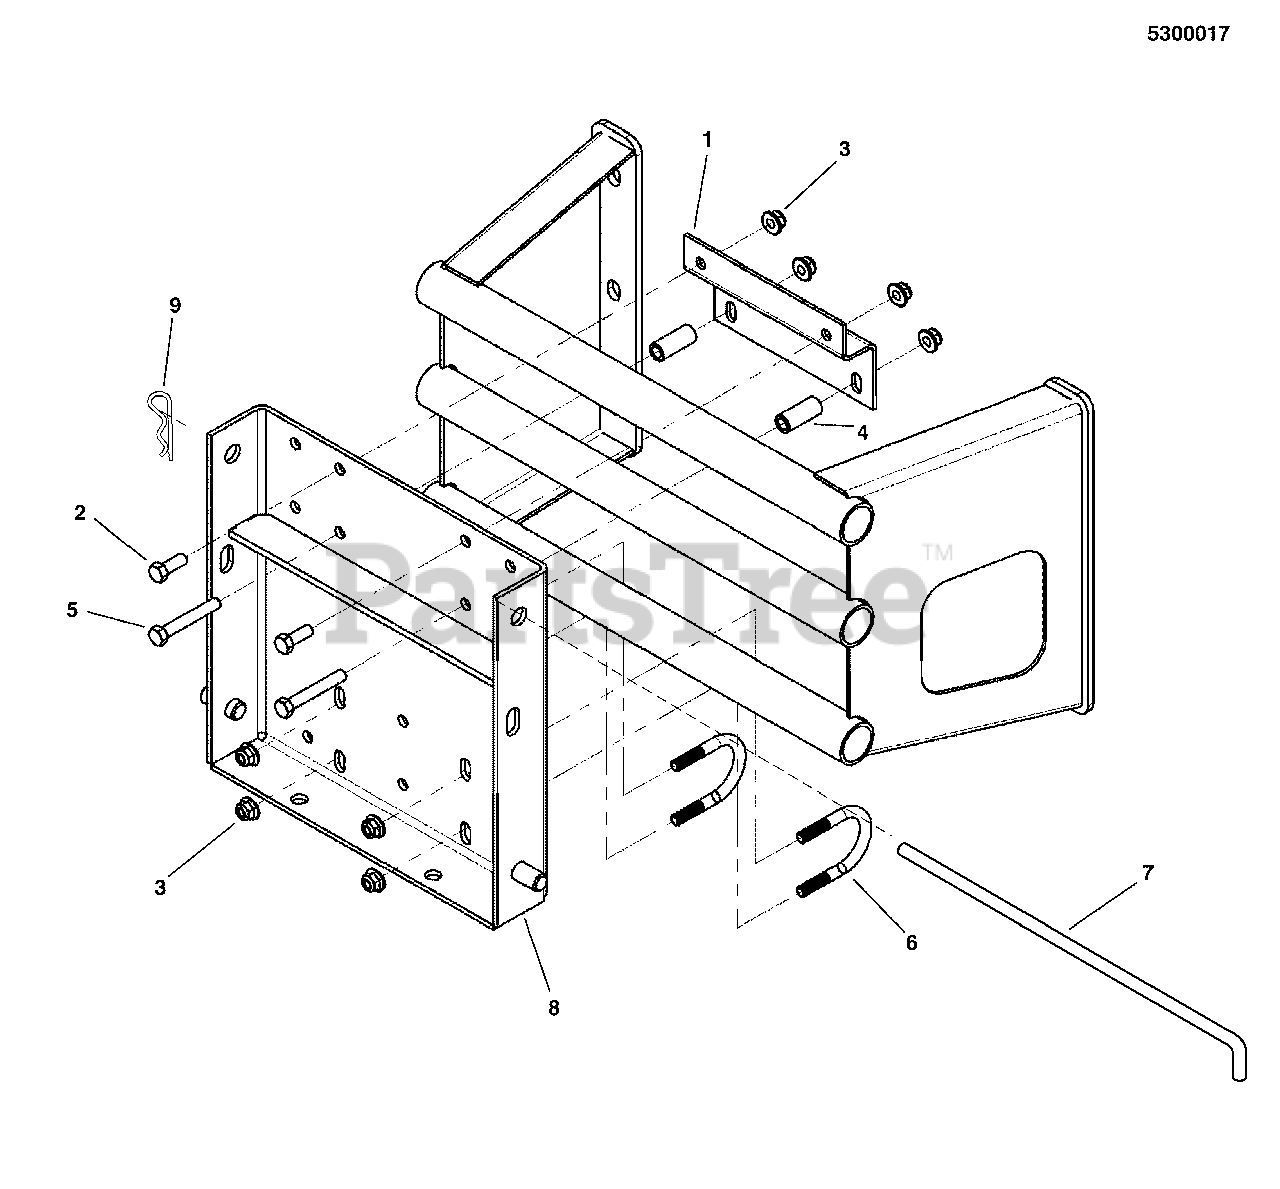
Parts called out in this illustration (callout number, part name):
1	ADAPTER PLATE
2	BOLT, 3/8-16 x 1
3	NUT, 3/8-16 HEX NYLOCK FLANGE
5	BOLT, 3/8-16 x 2-1/2
6	U-BOLT, 3/8 X 1-1/4
8	HITCH PLATE
9	HAIR PIN CLIP
